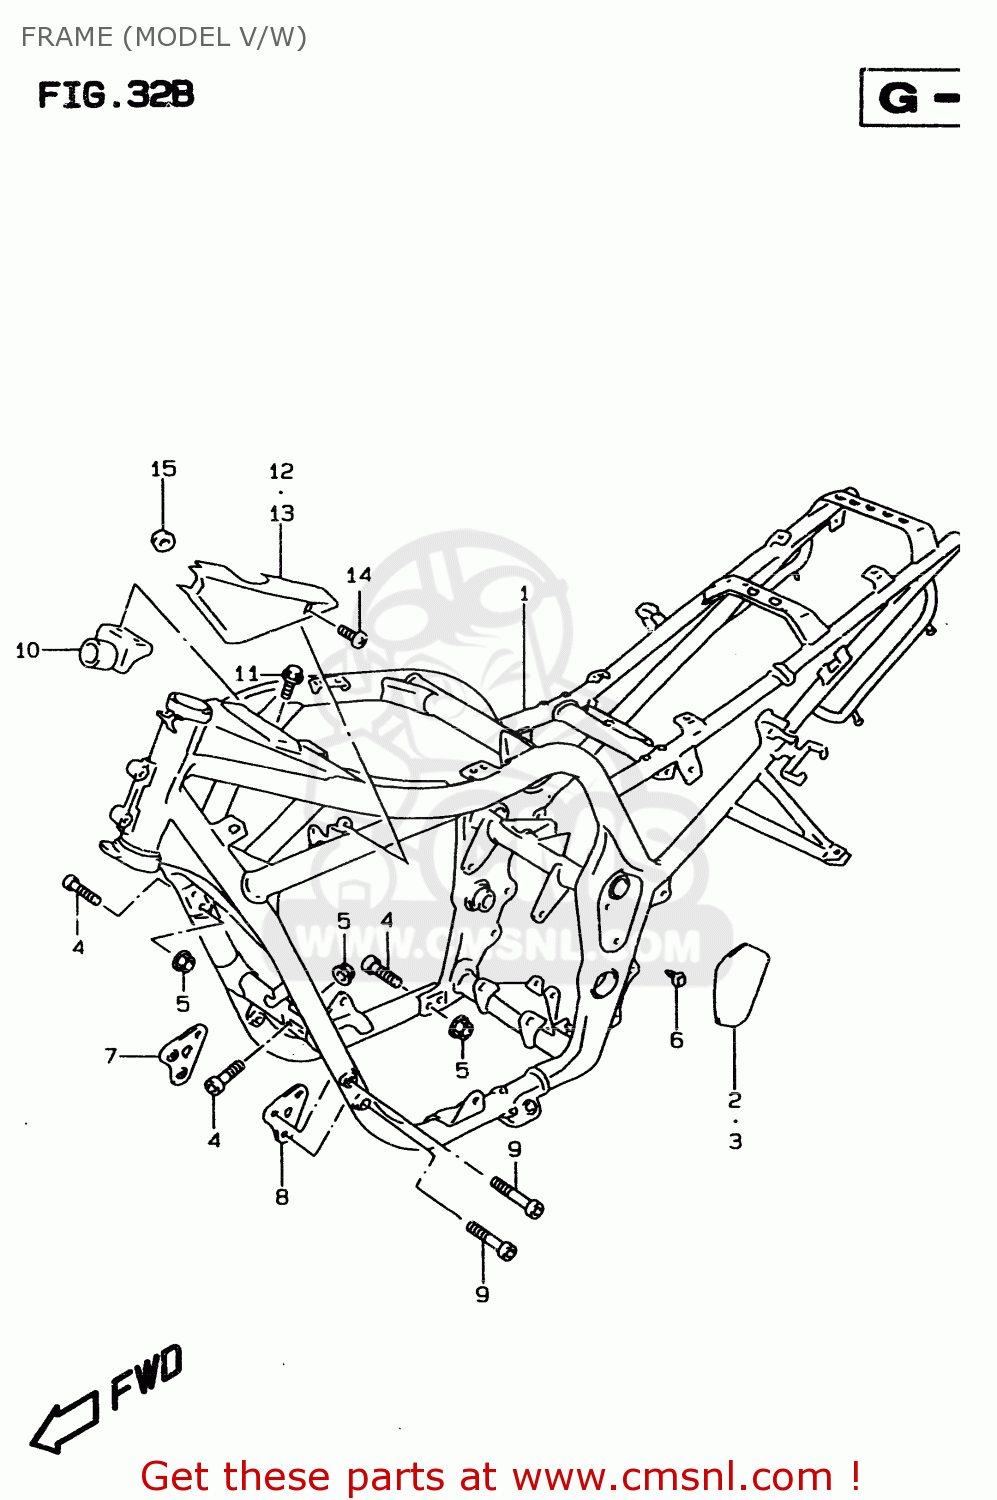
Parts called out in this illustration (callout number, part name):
1	FRAME COMP
2	COVER,FRAME BODY,R
3	COVER,FRAME BODY,L
4	BOLT(10X33)
5	NUT
6	CLIP
7	PLATE,ENG MTG,R
8	PLATE,ENG MTG,L
9	BOLT
10	DAMPER,FRAME
11	BOLT
12	COVER,FRAME HEAD,R
13	COVER,FRAME HEAD,L
14	SCREW(5X12)
15	CUSHION
